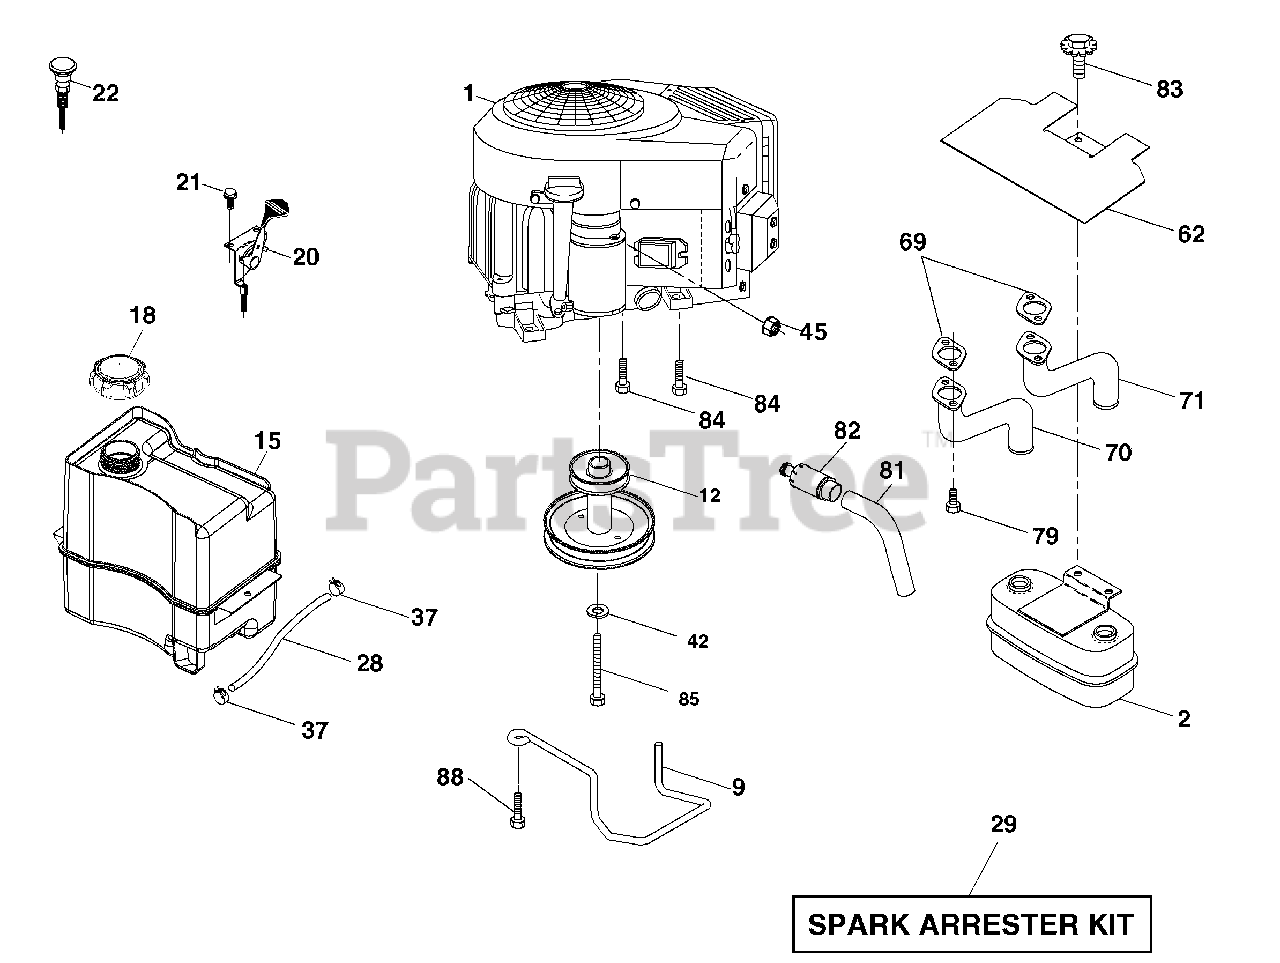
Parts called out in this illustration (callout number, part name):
9	Keeper Belt Engine
11	Clutch Ogura
12	Pulley Engine
15	Tank Fuel
18	Cap Asm
20	Control Throttle
21	Screw 10 x 3/4 Single Lead-Hex
22	Control Choke
28	Fuel Line
29	Spark Arrester Kit
31	Clip Push-In Hinged
37	Clamp Hose
41	Washer 1-1/2 OD x 15/32 ID x .250
42	Washer Lock 7/16
45	Nut Keps Hex 1/4-20 unc
62	Shield Heat Muffl er
70	Exhaust Tube LH
71	Exhaust Tube RH
79	Screw Socket Head 5/16-18 x 1
81	Tube Drain Oil Easy
82	Plug Drain Oil
83	Bolt 5/16-18 unc x 3/4 w/Sems
84	Screw 3/8-16 x 1-1/4
85	Bolt Hex 7/16-20 x 4 x Gr. 5-1.5 Thr
90	Screw 3/8-16 x 1
